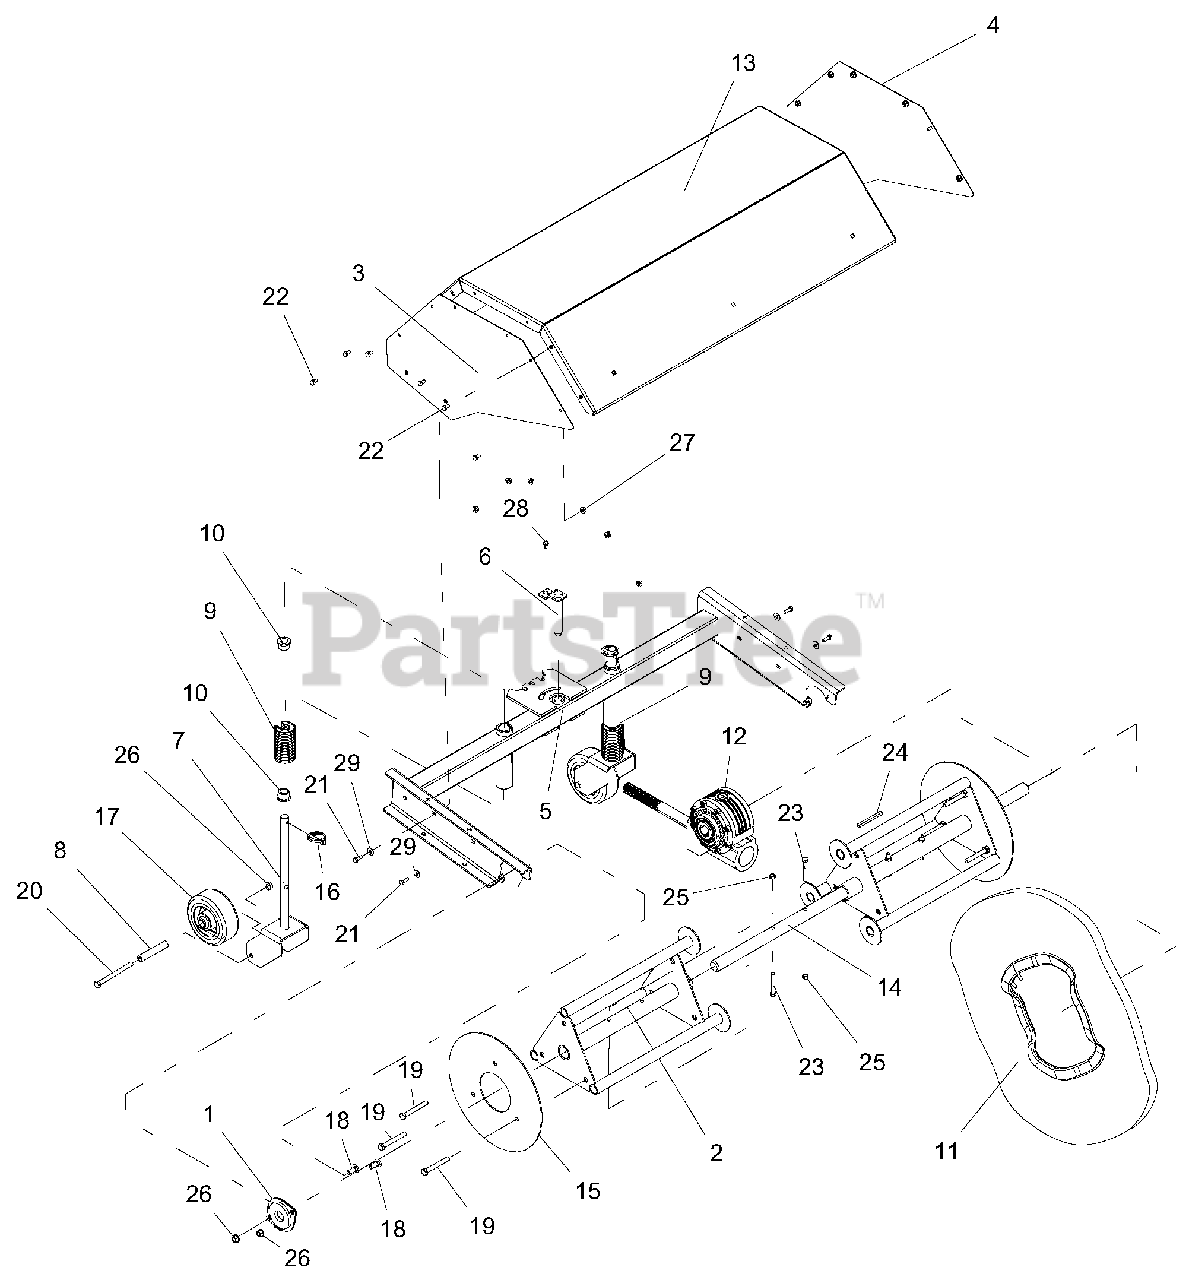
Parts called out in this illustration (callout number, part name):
1	BEARING,2 BOLT FLANGE 1-1/8 ID
2	BRUSH, DRIVE CORE
3	WLDT, SIDE COVER - RH
4	WLDT, SIDE COVER - LH
5	FRAME, POWER BROOM 36"
6	WLDMT, BRUSH PIN
7	FORK, CASTER
8	SPACER, CASTER WHEEL
9	CLIP-HOC FIXED
10	BUSHING, FLANGE .75X.75X1.0
11	KIT, BRISTLE - SET OF 18
12	GEARBOX, WORM - 8.25:1
13	COVER, TOP - 36" BRUSH W/DECAL
14	CENTER, SHAFT
15	PLATE, END RETAINER
16	PIN, 1/4X1-9/16 LYNCH
17	WHEEL, CASTER - 5"OD
18	@BLT-RDHDSQNK .38-16X1.00 G5YZ
19	BLT-HEX .38-16X3.00 GR5 FTH YZ
20	@BLT-HEX .38-16X4.50 GR5 YWZC
21	@BLT-HEX .25-20X.75 GR5 YWZC
22	@BLT-HEX .25-20X.50 GR5 YWZC
23	@BLT-HEX .31-18X2.25 GR5 YWZC
24	KEY .25 X .25 X 3IN
25	@NUT-LK-CTR .31-18 YWZC
26	@NUT-LK-TOP-FLG .38-16 YWZC
27	@NUT-LK-TOP-FLG .25-20 YWZC
28	SCR-TAP .25-20X.50 HWH TR YWZ
29	@WSHR-FL-STL.312X.734X.065 YWZ
